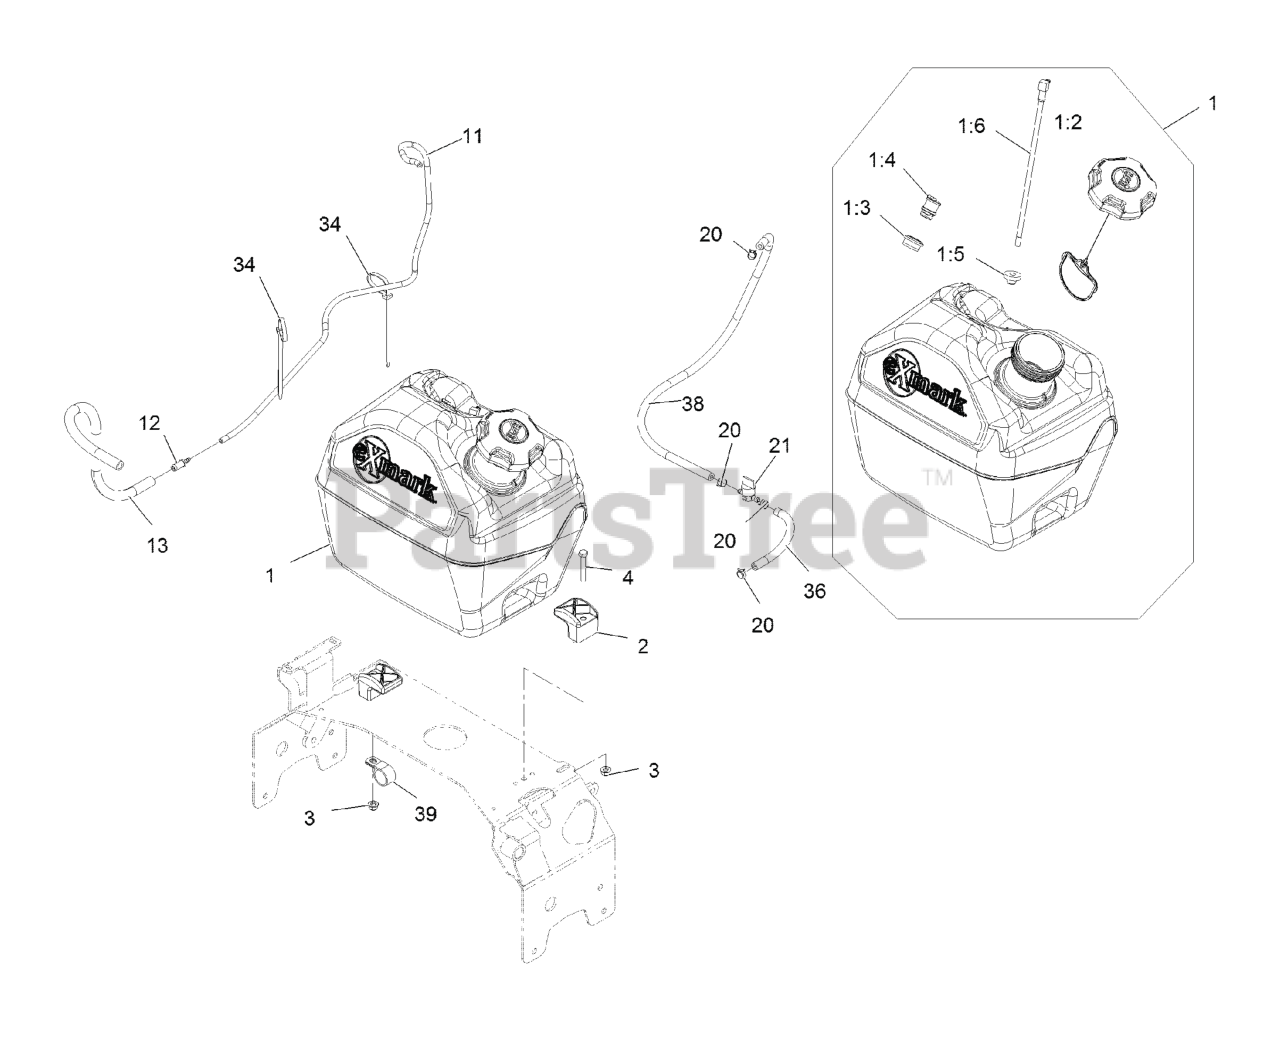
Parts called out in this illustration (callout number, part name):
1	ASM, FUEL TANK 5 GAL
1:2	CAP-FUEL, RATCHETING
1:3	GROMMET
1:4	VALVE-VENT, FUEL
1:5	BUSHING
3	NUT-HF, NI
4	SCREW-HH
11	HOSE, EMISSIONS
12	FITTING-STRAIGHT
13	HOSE-FUEL
20	CLAMP-HOSE
21	VALVE-FUEL
34	TIE-PLASTIC
36	HOSE-FUEL
38	HOSE-FUEL
39	CLIP-LOOM
